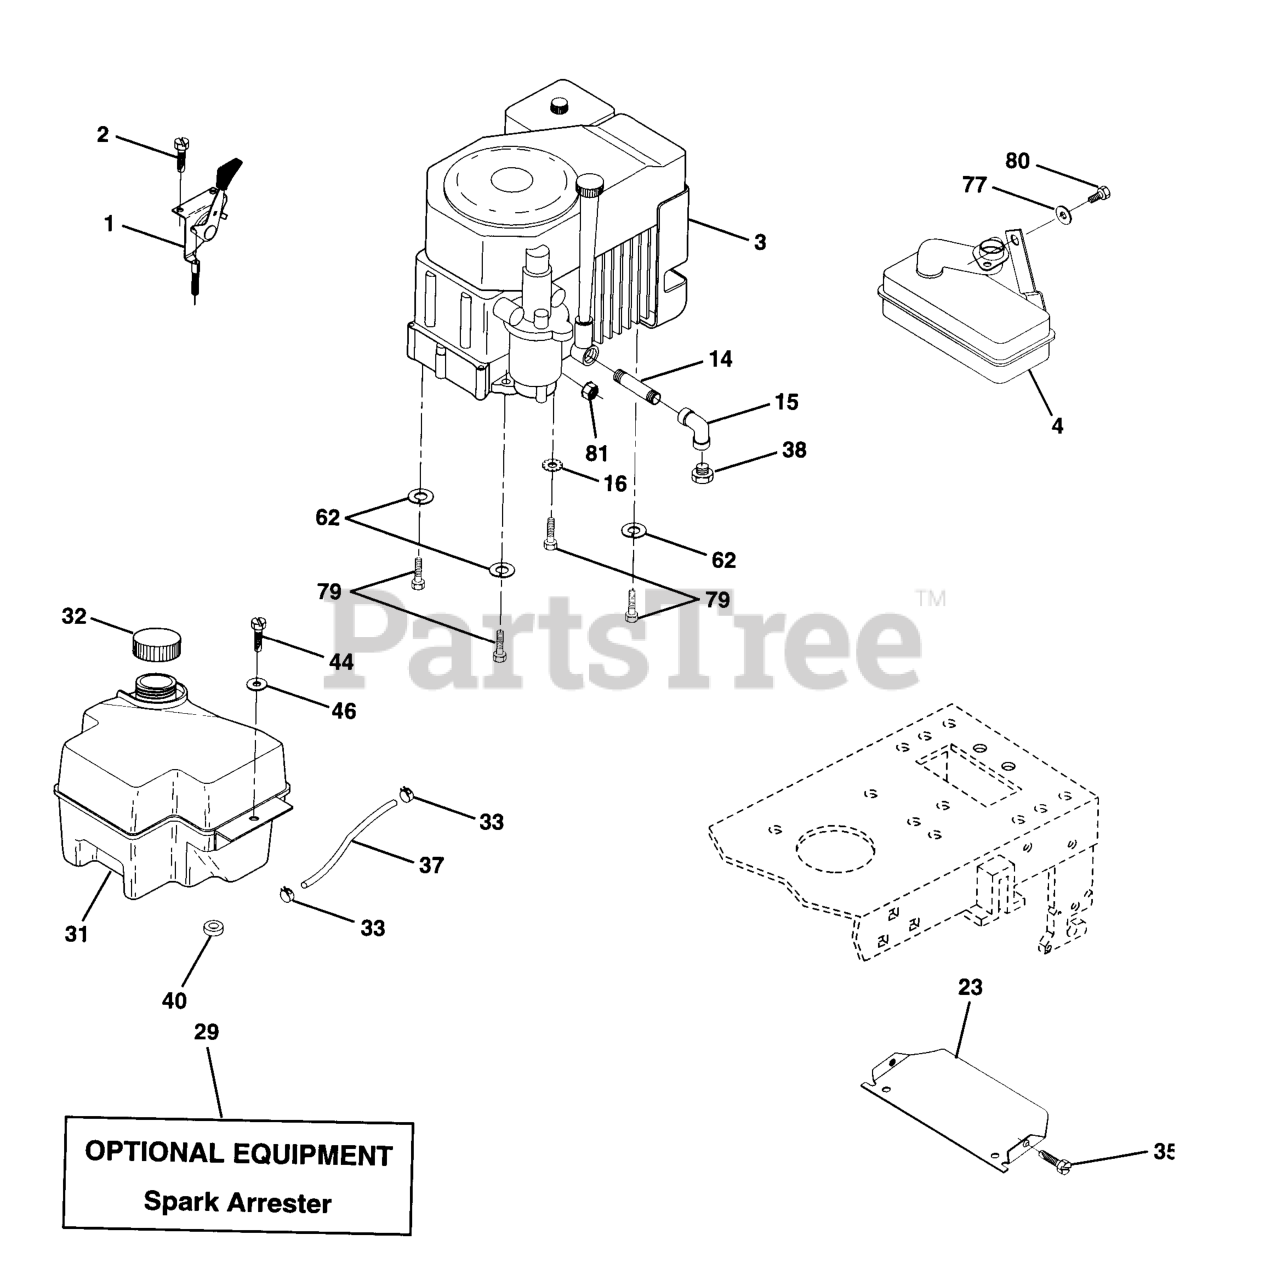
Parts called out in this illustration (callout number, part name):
1	CONTROL SWITCH 27 LH
2	SCREW LT
3	Engine Kohler, Model No. CV15S 15 HP
4	MUFFLER LT 12.5
14	Nipple Pipe 3/8 Npt x 3-1/2
15	ELBOW
16	WASHER EXT TOOTH LOCK 5/16
23	SHIELD HEAT
29	KIT.SPARK ARRESTOR 794945 B&S
31	FUEL TANK
32	FUEL CAP
33	HOSE CLAMP
35	SCREW.THDROL.5/16-18X3/4.TTY
37	LINE.FUEL.20
38	Plug Oil Drain
40	BUSHING.SNAP.NYL.BLK.
44	SCREW HEX CRT
46	WASHER
62	WASHER.LOCK.HVY.HLCL.SPR.5/16
77	WASHER
79	BOLT, HEX
80	Bolt Hex Hd 5/16-18 UNC x 1/2
81	NUT FLANGE 1/4-20 STARTER NUT
